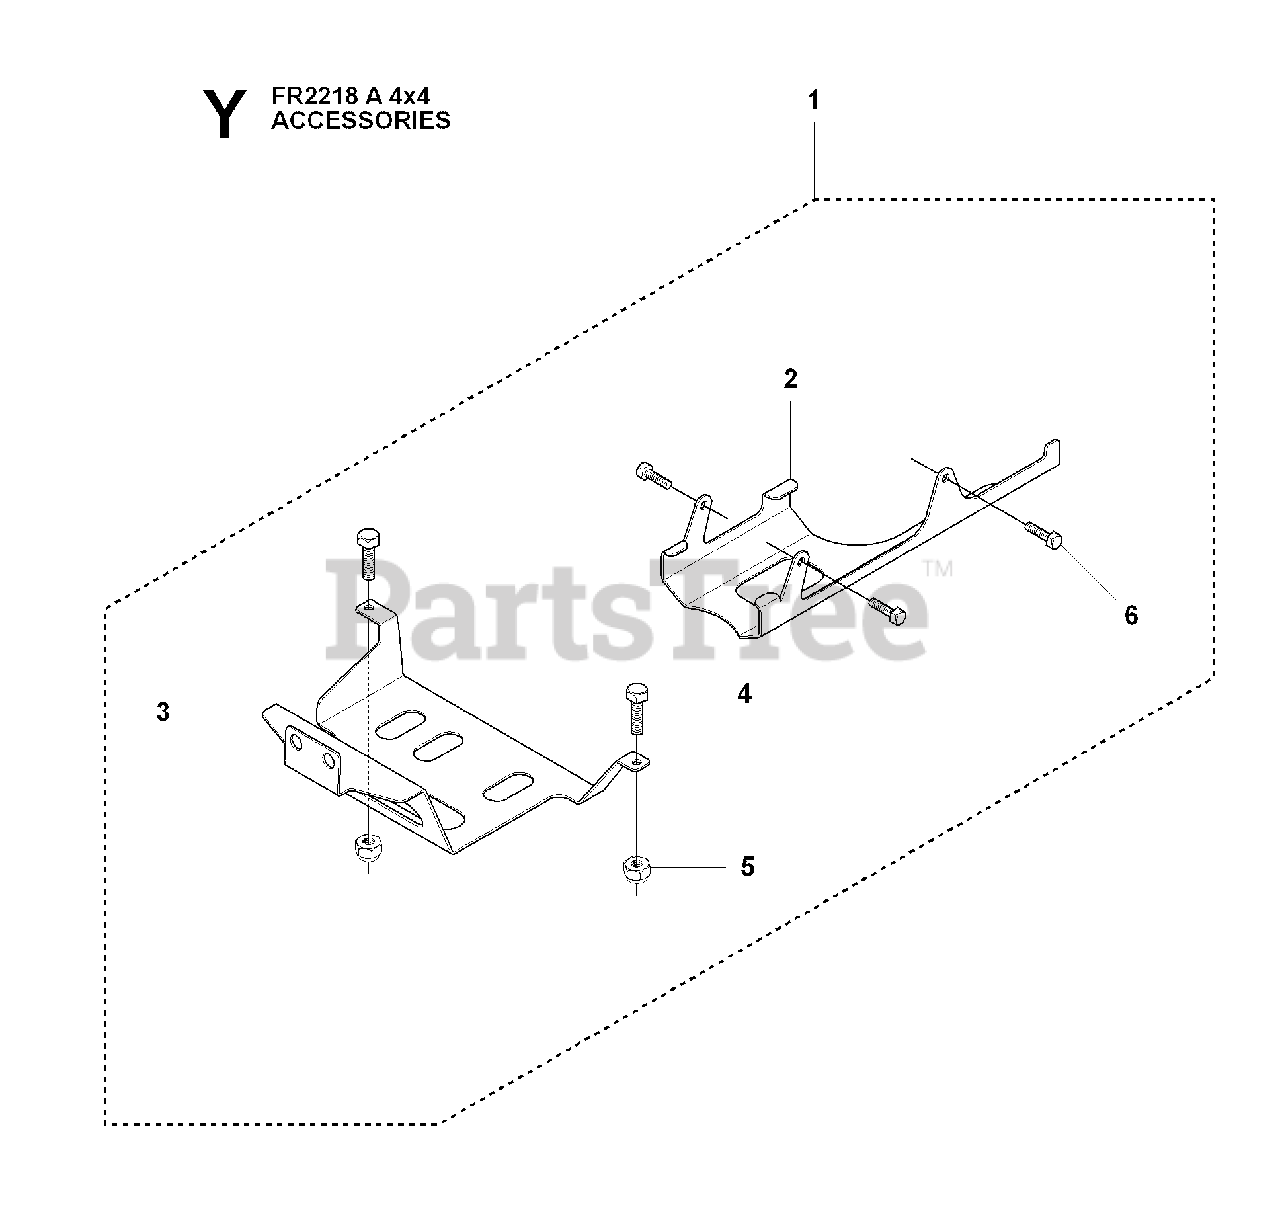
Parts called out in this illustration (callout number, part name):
3	RP PROTECTION PLATE REAR
5	LOCKNUT M8
6	BOLT FLANGE - M8X16
